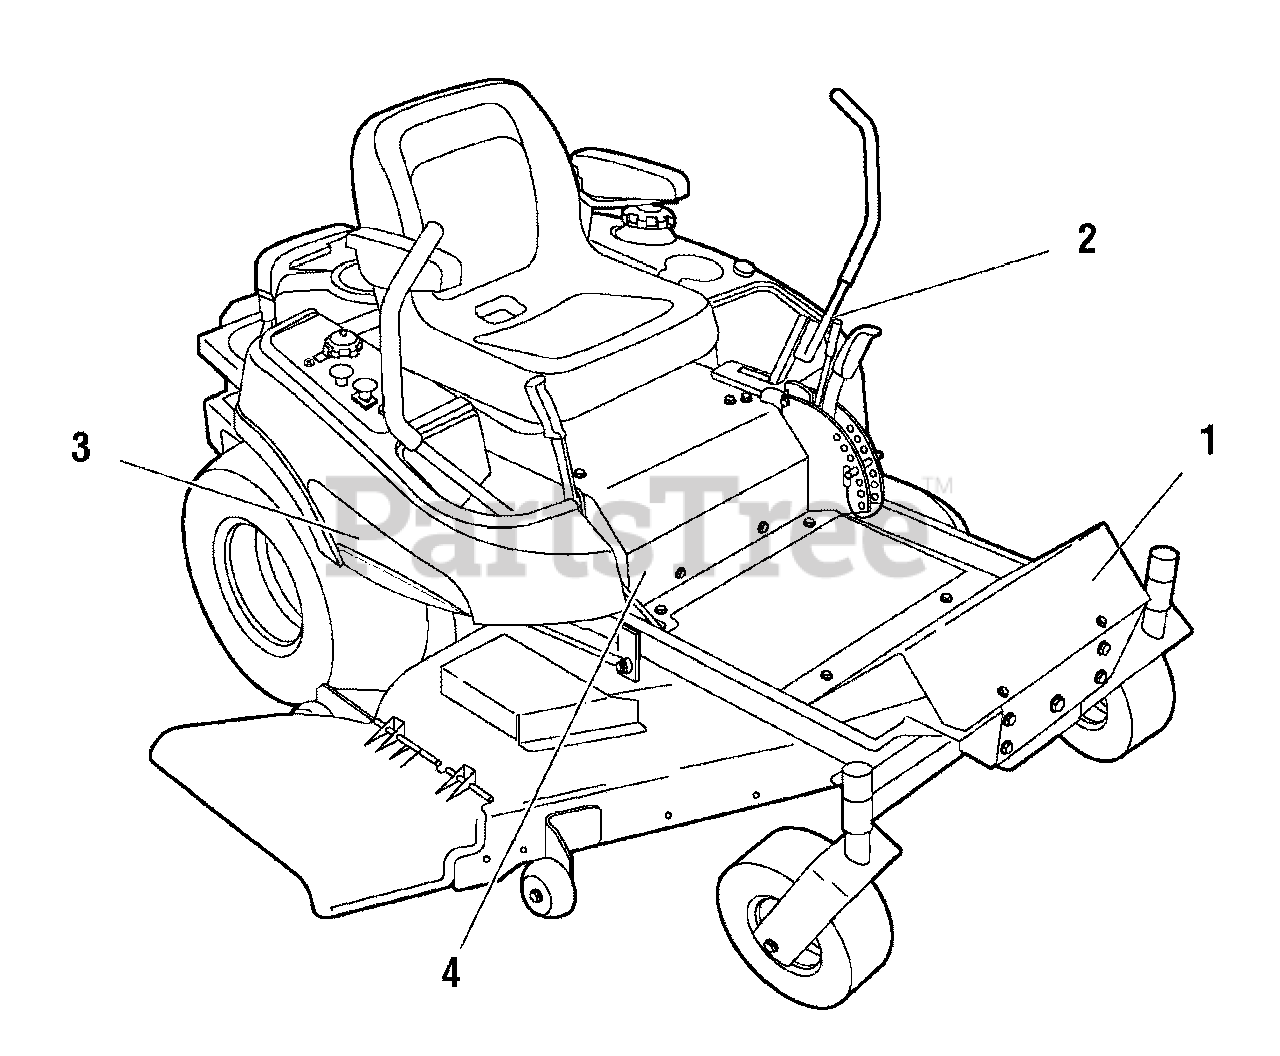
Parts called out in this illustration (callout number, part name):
1	DECAL, SNAPPER, SILVER & BLACK, 8.5"
2	DECAL, STRIPE, LH, SNAPPER
3	DECAL, STRIPE, RH, SNAPPER
4	DECAL, 400Z 24HP
